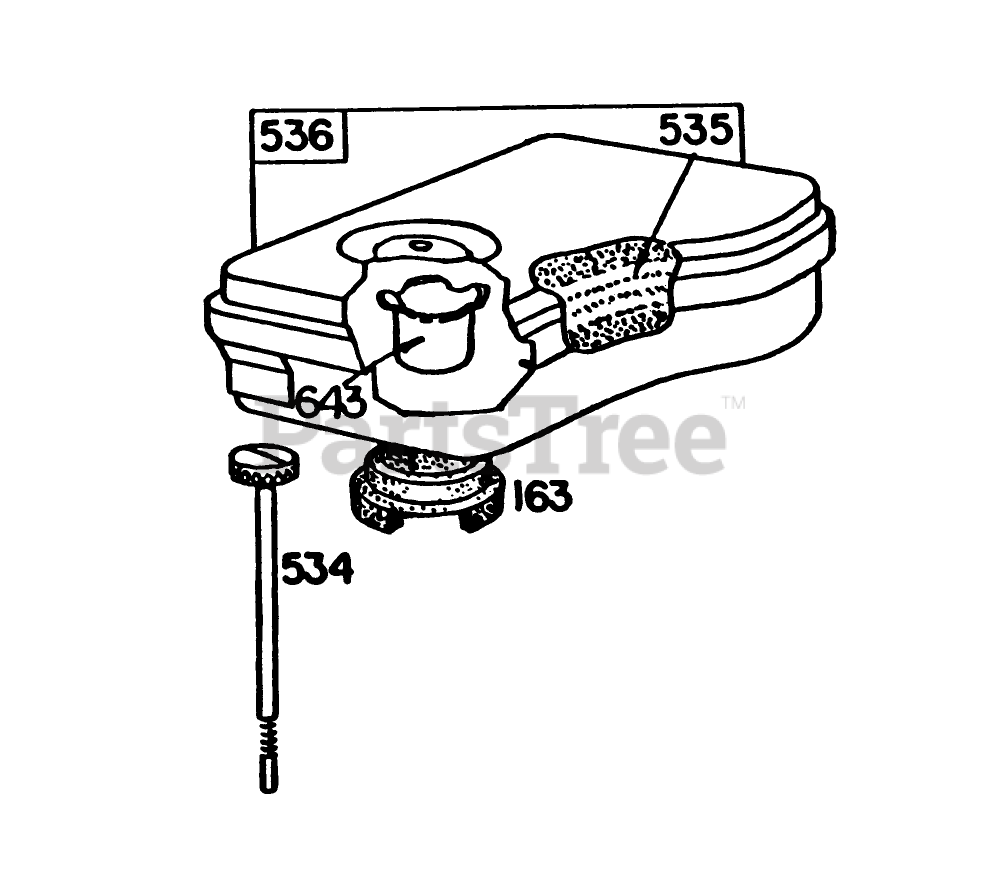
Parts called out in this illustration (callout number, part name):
163	51048 SUP.SHEET TIL
534	Screw-Air Cleaner
535	Element-Air Cleaner
536	Cleaner Assembly-Air
643	Cup-Support
